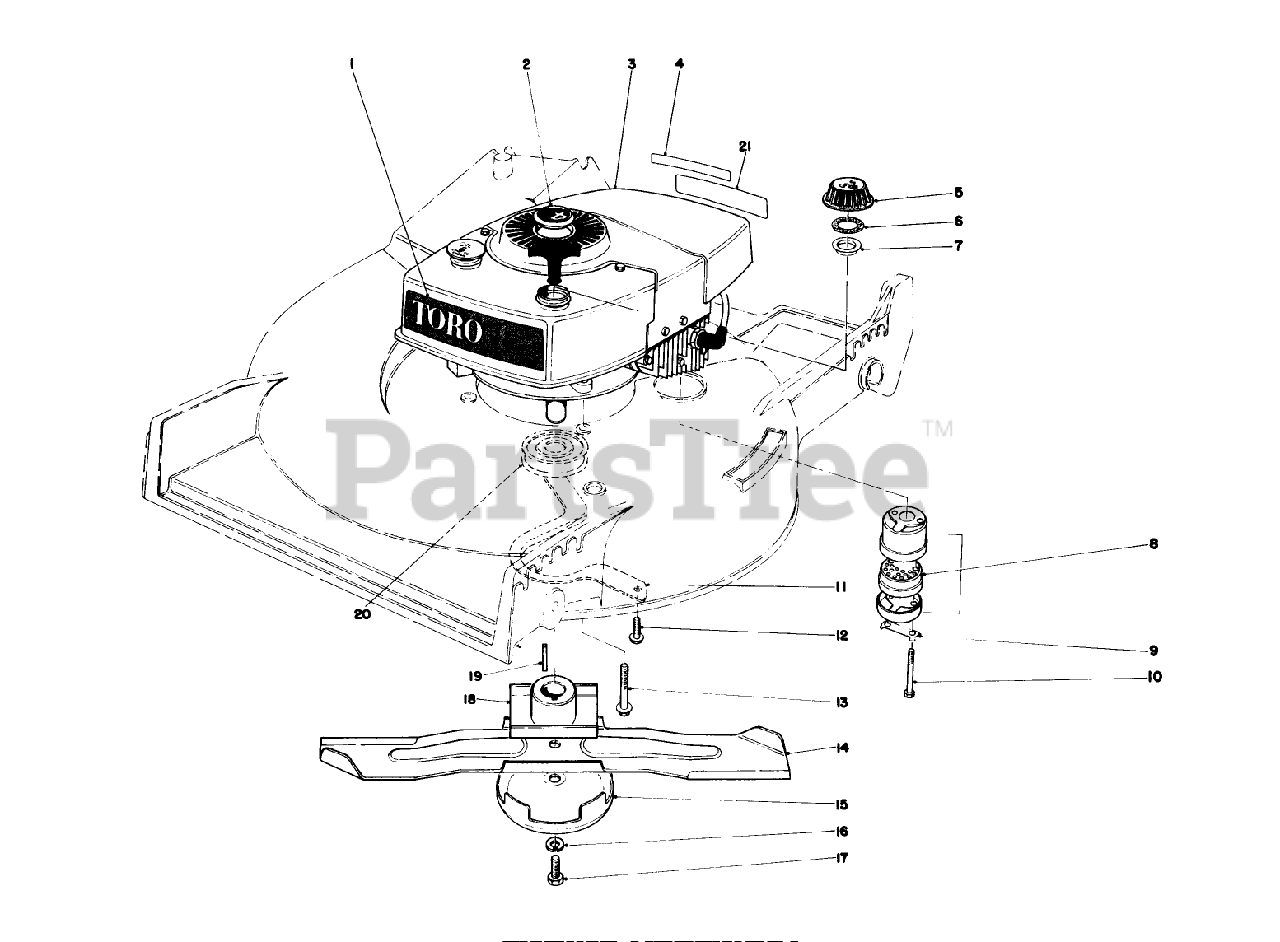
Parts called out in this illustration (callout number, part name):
1	Decal Toro
2	Plug Button
3	Engine
4	Decal-Primer Bulb
5	Gas Cap (Incl. Ref. #6 & 7)
6	GASKET
7	GAS CAP BAFFLE
8	Muffler Assembly (Incl. Ref. #9 & 10)
9	CLIP - LOCKING
10	SCREW-HH
11	BELT GUIDE
12	Screw
13	SCREW-HWHTF
14	Blade
15	AntiScalp Cup
16	WASHER-LOCK
17	BLADE SCREW
18	BLADE RETAINER WA(BLACK)
19	KEY-SQUARE
20	DRIVER PULLEY
21	Decal Maintenance
